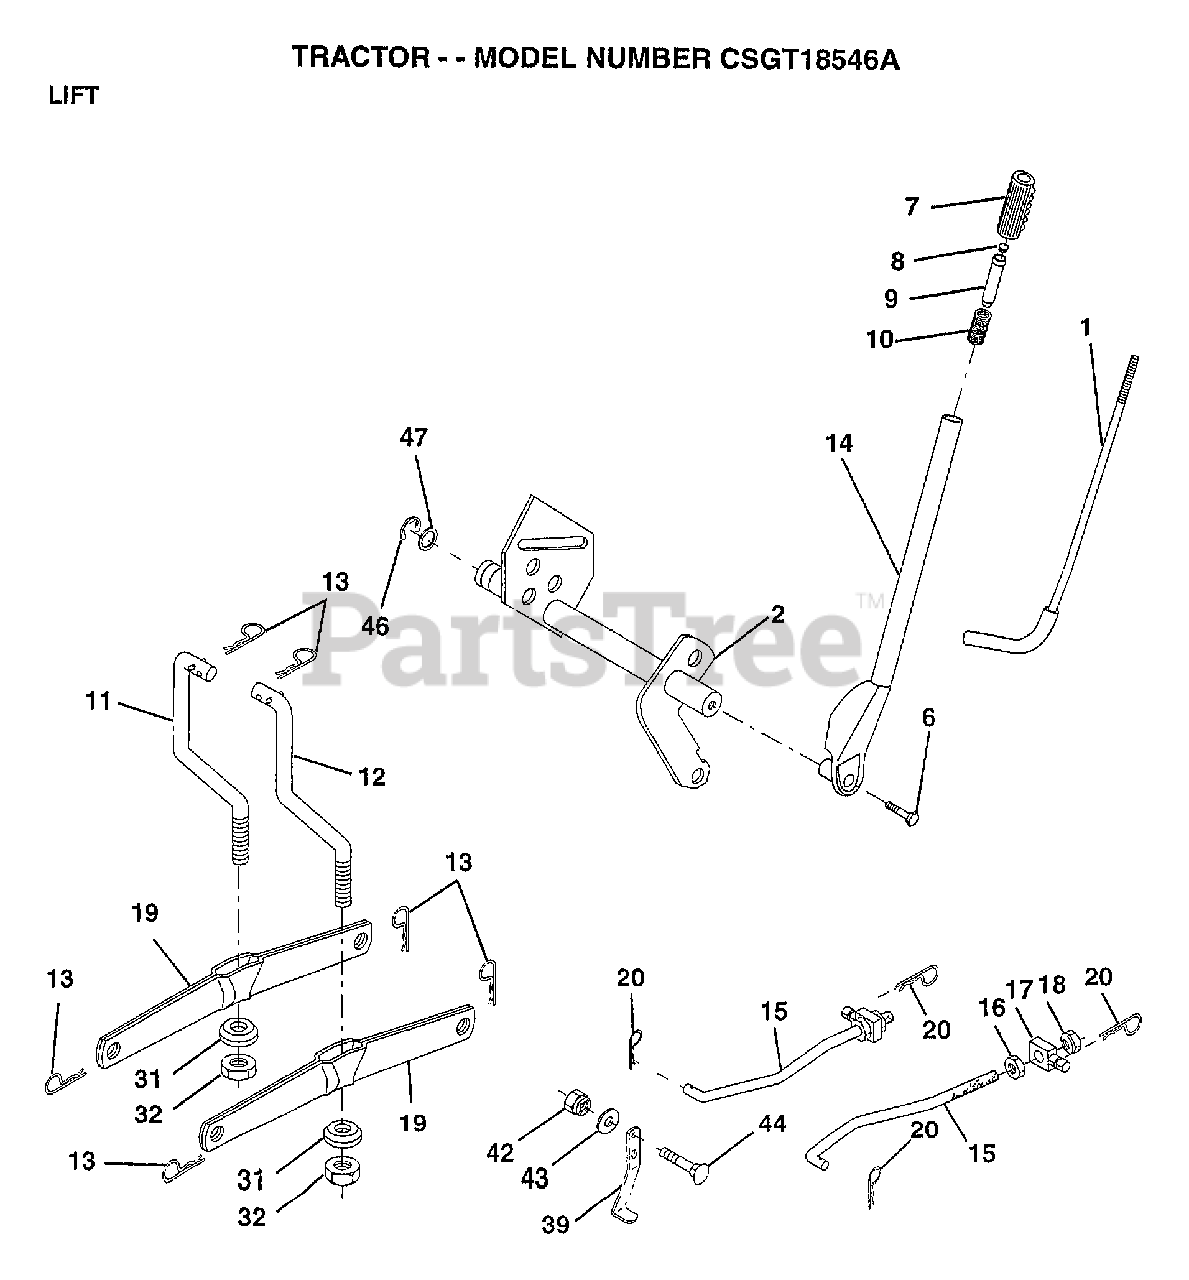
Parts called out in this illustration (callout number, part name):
1	LEVER ROD LT
2	SHAFT LIFT W/IND
6	"BOLT,HEX"
7	GRIP
10	SPRING T
11	LINK.LIFT.LH.GTV
12	LINK.LIFT.RH.GTV.
15	LINK.FRONT
16	NUT
17	TRUNION
18	NUT.LK.W/WSH.1/2.
19	ARM SUSP REAR
20	RETAINER.SPRING
31	BEARING PVT LH
32	NUT.CROWNLOCK.3/8
39	STOP.OVER.CENTER
43	WASHER GT
44	BOLT
46	E-RING
47	WASHER
